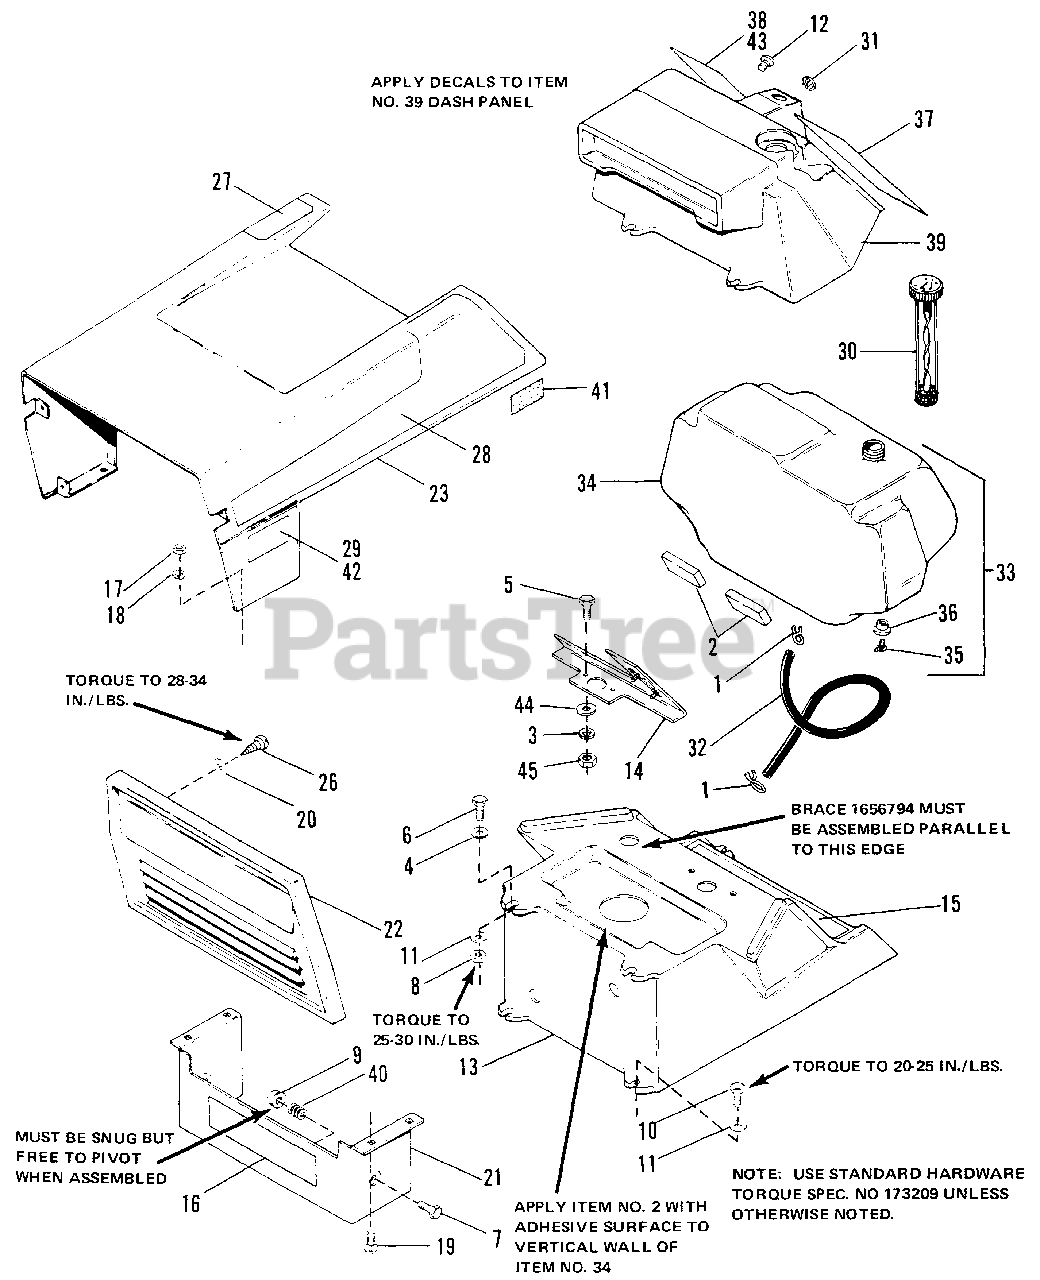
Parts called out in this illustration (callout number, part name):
1	CLAMP, Hose
2	PAD, Fuel Tank
3	LOCKWASHER, Spring, 3/8
4	WASHER, Plain, 1/4
5	CAPSCREW, Hex Hd., 3/8-16 x 1 Gr. 5
6	CAPSCREW, Hex Hd., 1/4-20 x 1-1/4 Gr. 5
7	* CAPSCREW, Hex Hd., 5/16-18 x 1-1/4 (10871)
8	NUT, Hex, Lock, 1/4-20
9	* NUT, Hex, Lock Flange, 5/16-18 (10871)
10	SCREW, Hex, Washer Hd., 1/4-20 x 1
11	WASHER, Lock, Dish Type, 1/4
12	SCREW, Phillips, 1/4-20 x 3/4
13	DASHBOARD, Bottom
14	BRACE ASSY, Dash
15	DECAL, Shift
16	DECAL, Simplicity
17	* NUT, Hex, 1/4-20 (10871)
18	* LOCKWASHER, Spring, 1/4 (10871)
19	* BOLT, Round Hd., 1/4-20 x 5/8 (10871)
20	* WASHER, Plain, No. 8 (10871)
21	* BUMPER (10871)
22	* GRILLE (10871)
23	* HOOD ASSY (10871)
26	* SCREW, Phillips, 10-32 x 3/8 (10871)
27	DECAL, Hood, R.H.
28	DECAL, Hood, L.H.
29	DECAL, "4108 Electric Start" (Electric Start)
30	CAP, Fuel Tank
31	CAP-PLUG, 1/2 Hole
33	FUEL TANK ASSY (Includes Ref. Nos. 34, 35, 36)
37	DECAL, Dash, L.H.
38	DECAL, Dash, R.H. (4108 Electric Start Only)
39	DASHBOARD,Top
40	* SPRING (10871)
41	* PAD, Felt (10871)
42	DECAL, "4108 Manual Start" (Manual Start)
43	DECAL, Dash, R.H. (4108 Manual Start Only)
44	WASHER, Plain
45	NUT, Hex, 3/8-16
